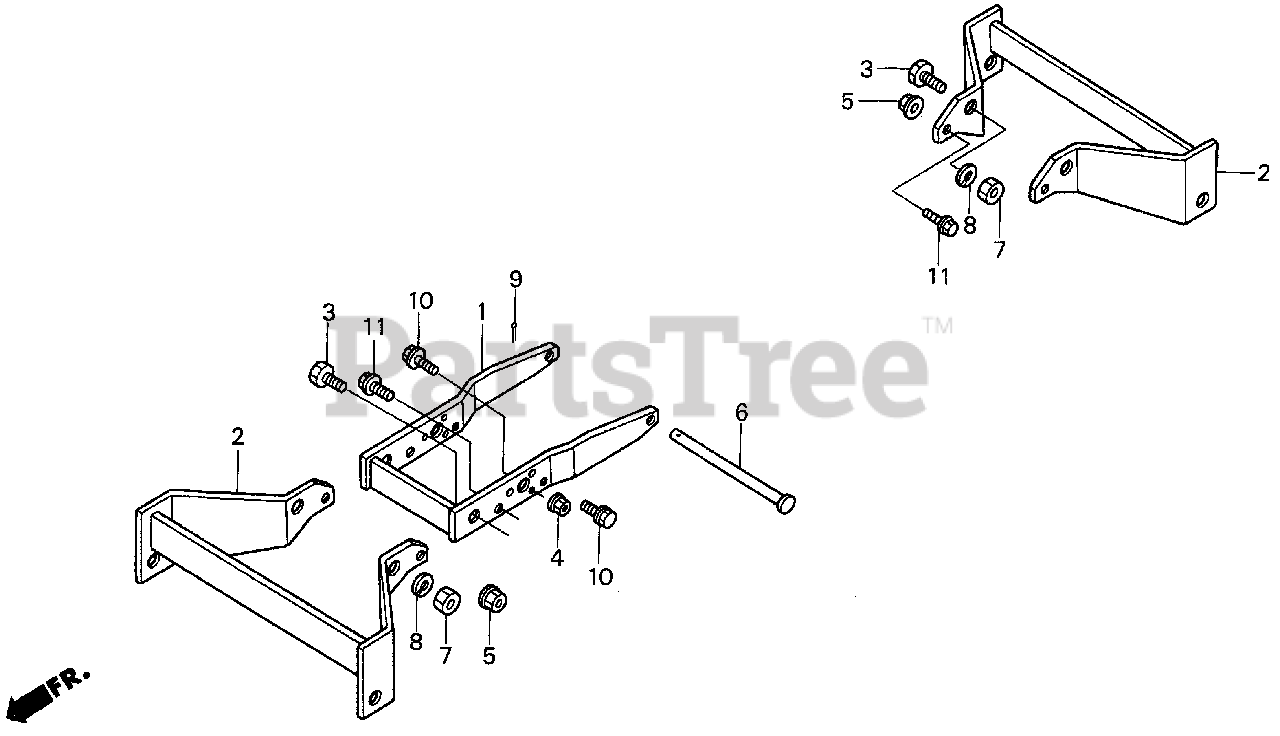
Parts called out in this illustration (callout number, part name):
1	BRACKET, FR. WEIGHT (NOT AVAILABLE)
2	BRACKET, WEIGHT
3	BOLT, HEX. (20X35)
4	NUT, SELF-LOCK (8MM)
5	NUT, SELF-LOCK (12MM) (SATO RASHI)
6	SHAFT, FR. HITCH
7	NUT, HEX. (20MM)
8	WASHER, SPRING (20MM)
9	PIN, SPLIT (3.0X45)
10	BOLT, FLANGE (8X25)
11	BOLT, FLANGE (12X30)
